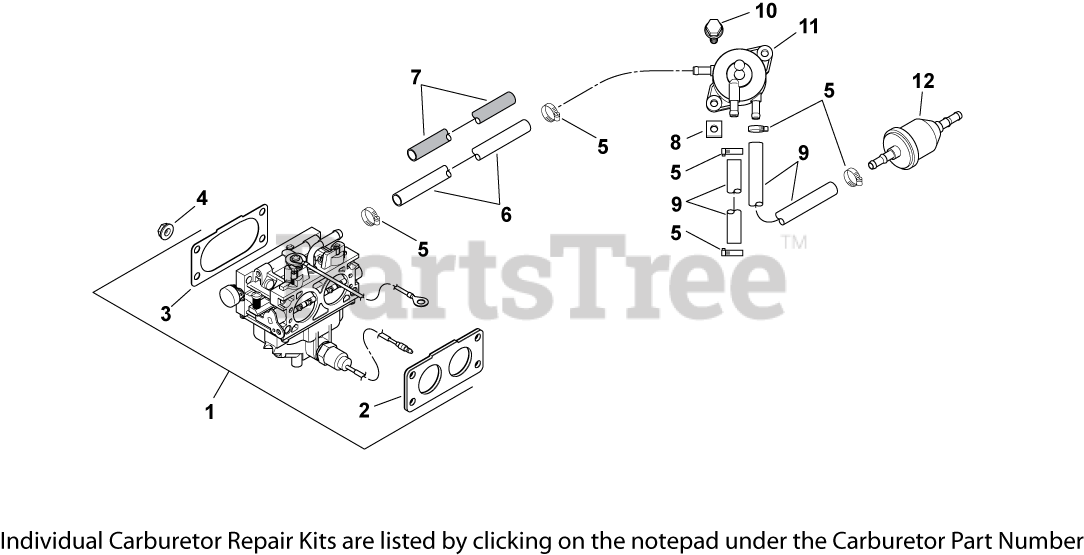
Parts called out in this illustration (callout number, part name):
1	CARBURETOR KIT-USE 24 853 111-S
2	GASKET, CARBURETOR - USE 24 041 82-S
3	GASKET, AIR CLEANER ELBOW
4	NUT, FLG M6X1.0
5	CLAMP, HOSE (KM)-USE 25 237 31-S
6	LINE, FUEL 11"
7	SLEEVE, INSULATING 14"
8	NUT, PLASTIC (KM)-USE 25 100 37-S
9	HOSE,LW PERM.FUEL 24.00"-USE 25 111 81-S
10	SCREW, TAP M6X1.7X18
11	PUMP, FUEL
12	FILTER, FUEL (9-12 MICRON)-USE 24 050 13
